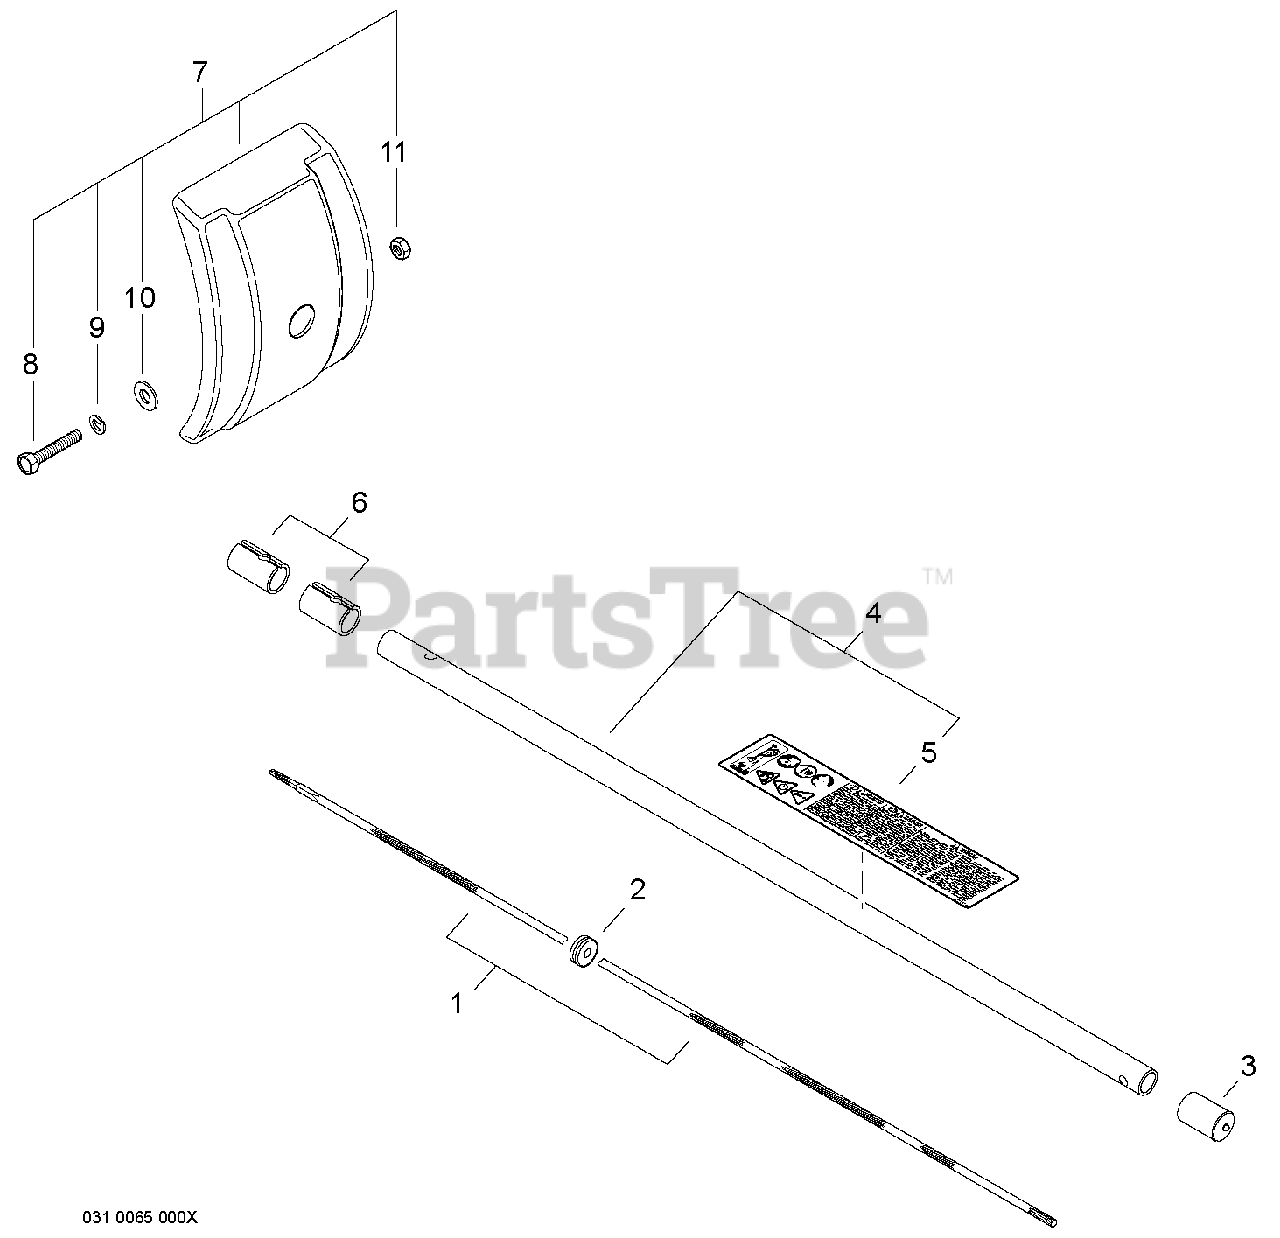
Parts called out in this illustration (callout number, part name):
1	DRIVESHAFT
2	BUSHING
3	CAP, MAIN PIPE
4	MAIN PIPE ASSY
5	LABEL - CAUTION
7	DEBRIS SHIELD KIT
8	BOLT - 6X20
9	LOCKWASHER - 6
10	WASHER - 6
11	LOCKNUT - 6
